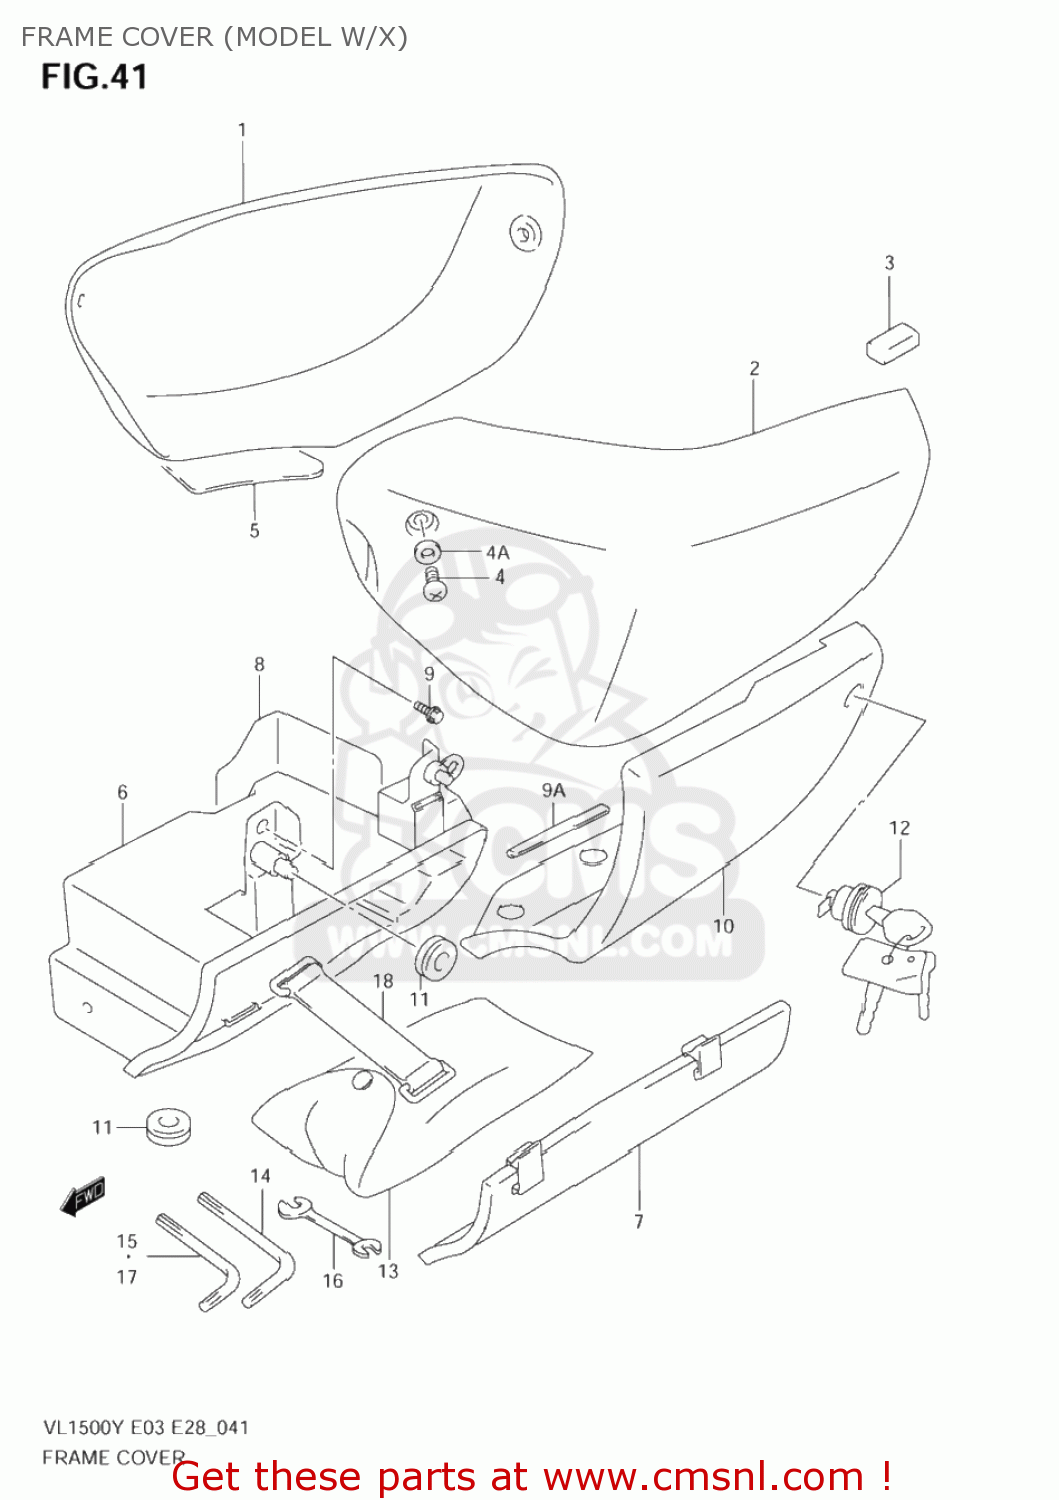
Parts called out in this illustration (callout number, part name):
1	COVER,FRAME,R(BLACK)
2	COVER,FRAME,L(BLACK)
3	CUSHION,FRAME COVER
4	SCREW(6X16)
4A	WASHER(6.5X15X1.0)
5	SHIELD,FRAME COVER,R
6	BODY,TOOL HOLDER
7	CAP,TOOL HOLDER
8	SHIELD,TOOL HOLDER BODY
9	BOLT(6X16)
9A	MOLDING,FRAME COVER,L
10	COVER,TOOL HOLDER
11	CUSHION
12	LOCK SET,COVER
13	TOOL ASSY
14	HEXAGON SPANNER,12
15	SPANNER,HEXAGON(4)
16	OPEN SPANNER(8X10)
17	HEXAGON SPANNER,5
18	BAND
